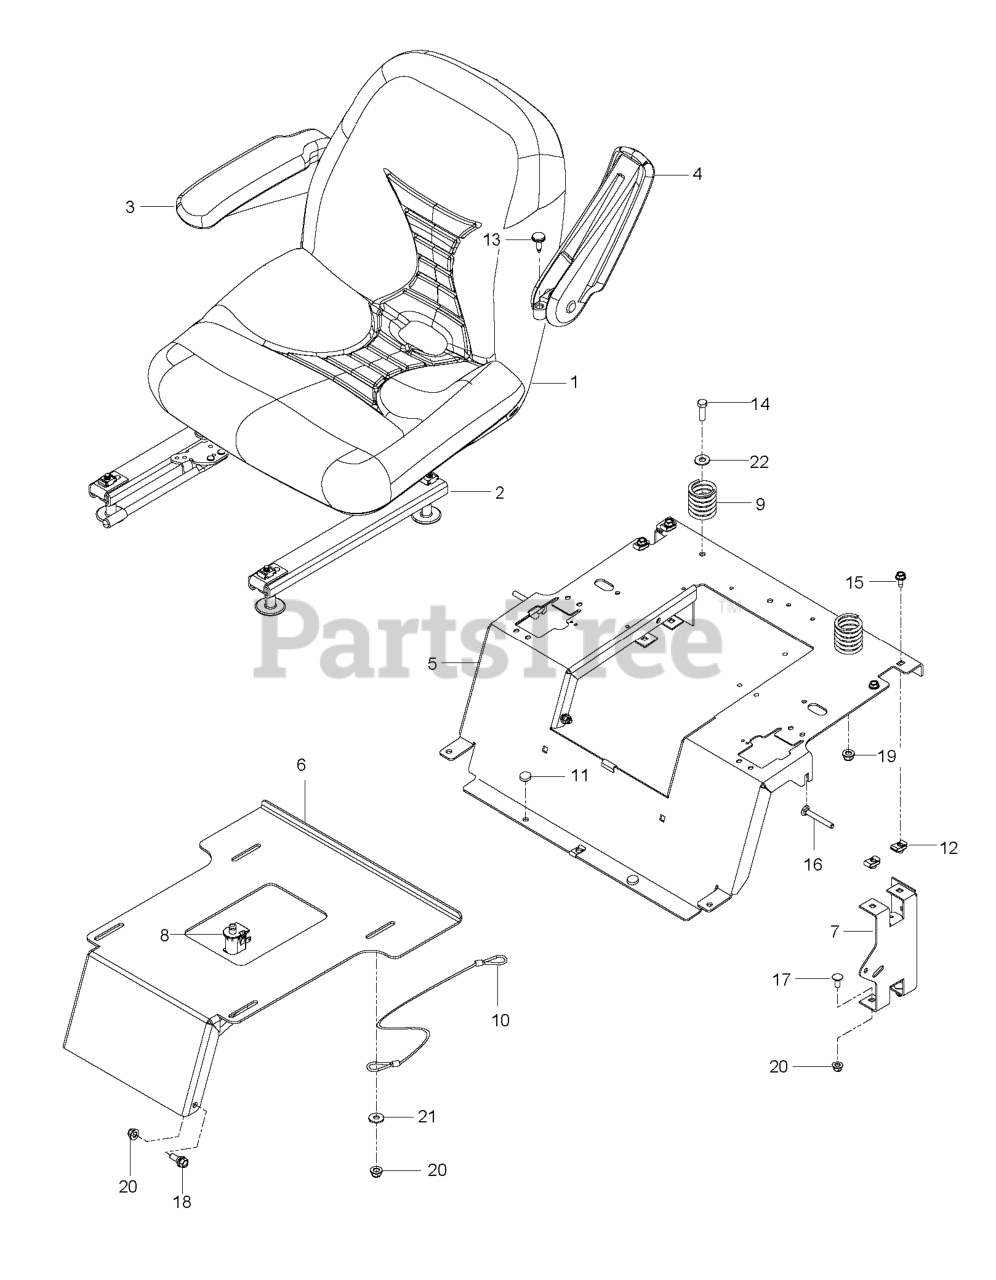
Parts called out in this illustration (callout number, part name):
1	SEAT
2	TRACK ADJUSTMENT KIT
3	ARMREST KIT, RT SQUARE END
4	ARMREST KIT, LT SQUARE END
5	SUPPORT SEAT FLAT ORANGE
6	PAN, SEAT ORG
7	SUPPORT REAR SEAT BLACK
8	SWITCH.SNAPMOUNT.NC
9	SPRING, SEAT
10	SEAT LANYARD
11	GROMMET, BUMPER
12	U-CLIP 5/16-18 NUT RETAINER
13	ADJUSTER KNOB
14	HCS 3/8C X 1 1/4 GR5
15	BOLT 5/16-18 X 3/4
16	RHSNB 5/16-18 X 2-1/2 GR5 ZD
17	BOLT 5/16C X 3/4" CARRIAGE
18	SB 5/16-18 HEX HD GD5, BLK ZN
19	NUT 3/8-16 NYLOC
20	5/16-18 NYLOC FLANGE NUT
21	WASHER 5/16 FLAT
22	WASHER 3/8 FLAT
